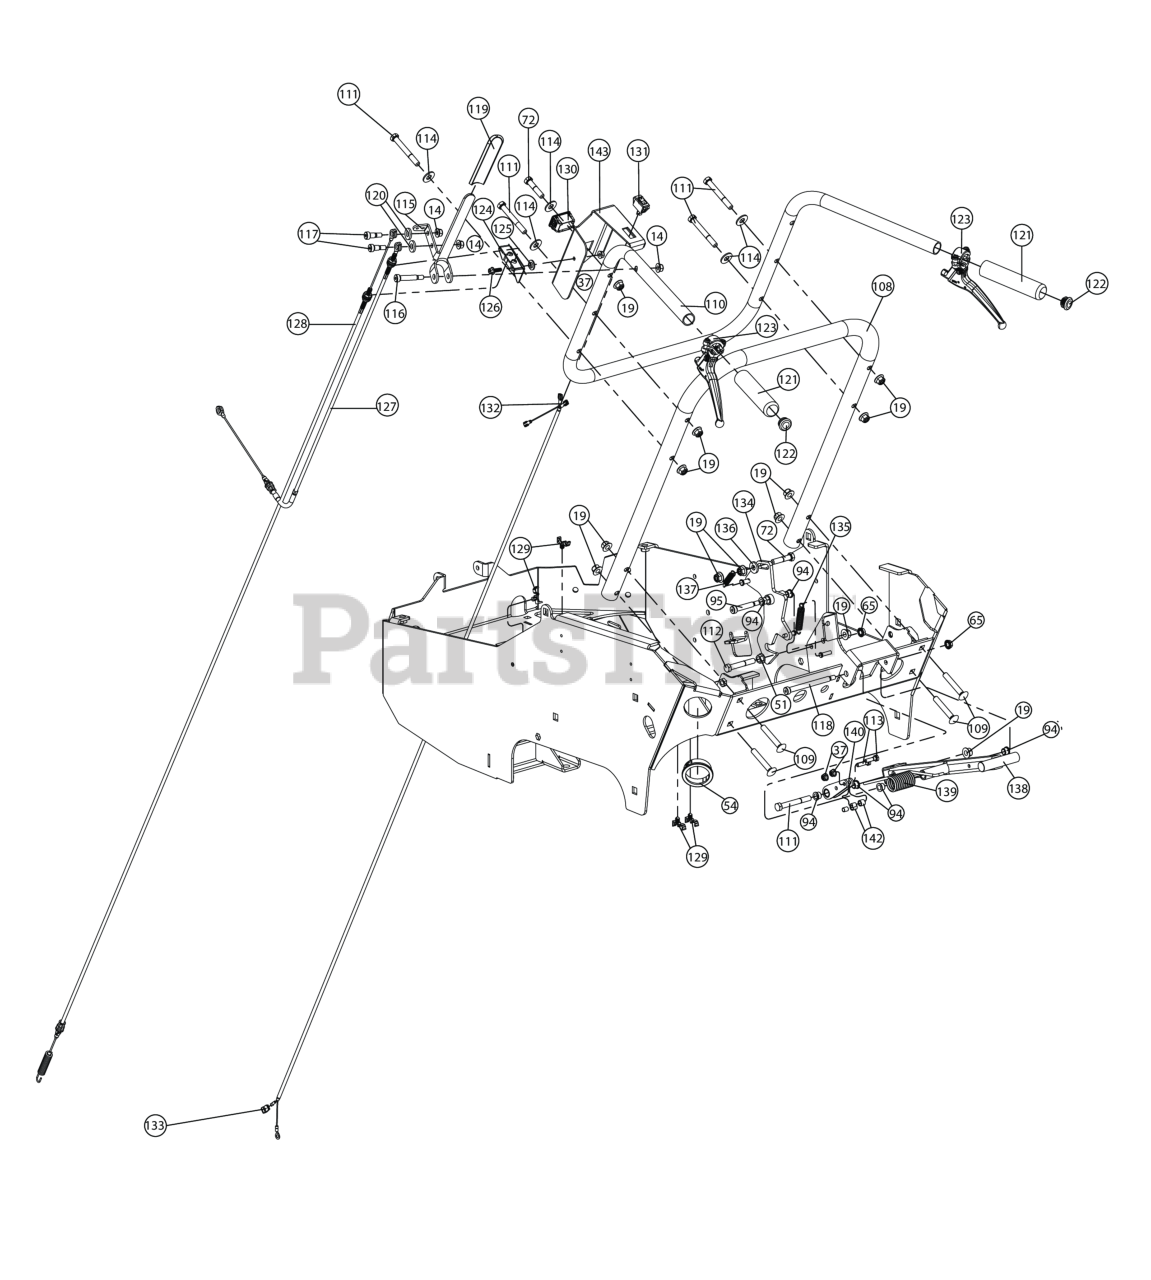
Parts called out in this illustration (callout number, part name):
14	NUT-HEX-NYLK, FLG .3125-18 ZP
19	NUT-HEX-NYLK, FLG .375"-16 ZP
37	NUT-HEX-NYLK, FLG .250"-20 ZP
51	NUT WASHER FACE
54	BUSHING, SNAP 1.81" ID
65	NUT FLANGE 5/16"-18 ZP
72	SCREWCAP 3/8"-16 X 1 3/4" HCS ZP
94	BUSHING 3/8 ID X 1/2 OD X 3/8
95	BOLT SHOULDER 3/8" X 1 3/4"
108	HANDLEBAR, LOWER PL2501
109	BOLT CARRIAGE 3/8-16 X 2 1/2" ZP
110	HANDLEBAR, UPPER PL2501
111	SCREWCAP 3/8"-16X3" HCS ZP
112	SCREWCAP 3/8"-16X2 1/2" HCS ZP
113	SCREWCAP 1/4"-20 X 1" HCS ZP
114	SCR-CAP, HEX .250"-20 X 0.750" G8 YZ
115	SEE: 351624
116	BOLT SHOULDER 3/8 X 1 1/2"
117	BLT-SLDR,SH.375"X.50",.313"-18X.50"G8ZP
118	BLT-SLDR,SH.375"X4.00",.313"-18X.50"G8ZP
119	GRIP LEVER 0.125" X 1" X 5" ORANGE
120	WSHR-STL, FLT, .406" X .875" X .125" ZP
121	GRIP HANDLE
122	PLUG TUBE INSERT 1" OD
123	CONTROL MAGURA
124	BRKT, CABLE MOUNT
125	WASHER, SHOULDER .265"X.437"X.125" NYL
126	SCR-MAC, HWH .250"-20 X .750" G2 ZP
127	CABLE, AUTO ENGAGE
128	CABLE, CLUTCH
129	CABLE CLAMP
130	HOURMETER, INDUCTIVE PANEL MOUNT
131	SWITCH LKG RKR B&S #493521
132	HARNESS, STOP SWITCH WIRE
133	TERMINAL 18-14 BLUE T-TAP
134	WA, TINE LATCH
135	SPRING EXTENSION 1/2 OD, 3-5"
136	WSHR-NYL, FLT, .385" X .880" X .125"
137	SPRING EXTENSION
138	WA, LIFT PEDAL
139	SPRING,TOR,Ø.865IDX.180"WDX0.702#-IN/°
140	WA, UPPER TINE LINK
142	BRG, SLEEVE .250" X .4375" X .375" BNZ
143	WA, SWITCH & HOUR METER MOUNT
